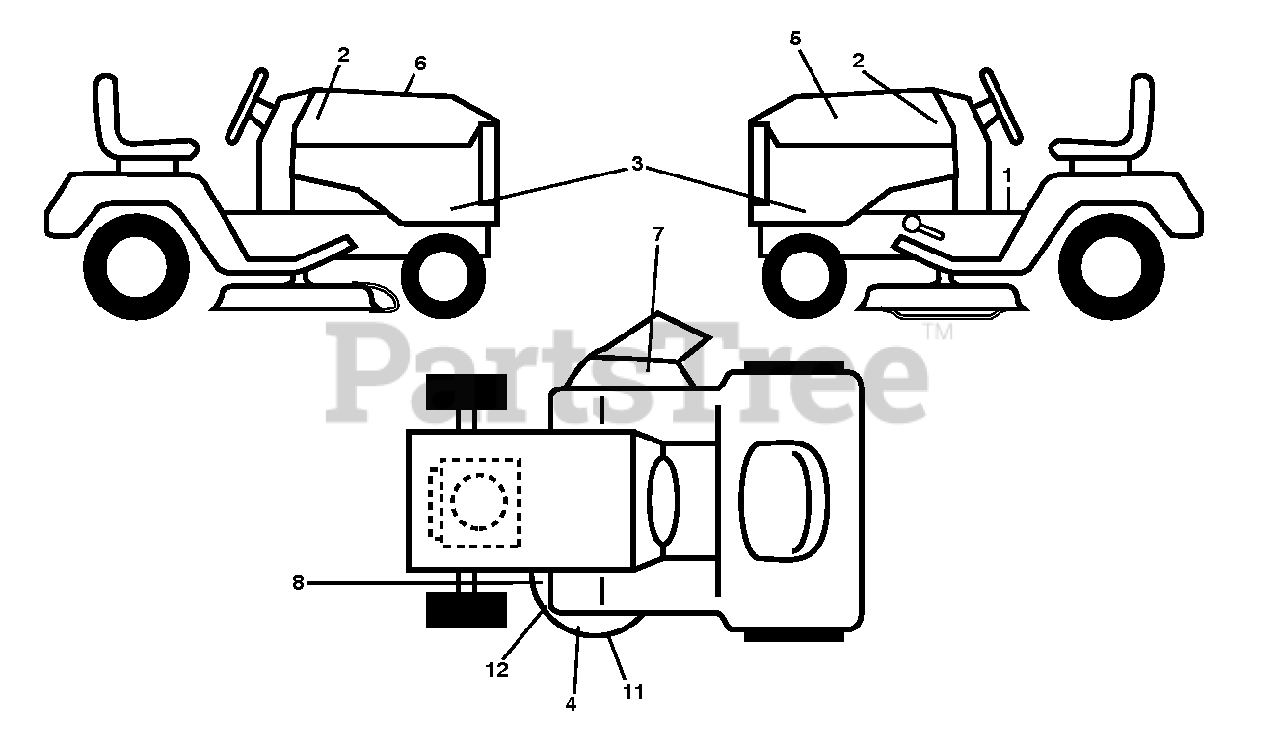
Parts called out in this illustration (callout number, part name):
1	DECAL.WARN.STARTINST.LOWEARIEN
2	DECAL.BADGE.170MM.TEXTLOGO.
3	Decal, Side Panel HUSQGT YT42DXL Set
4	DECAL.DECK.CLEARCUT.NOSTEP
5	DECAL.WARNING.CUST.RESP.E85.
6	DECAL.RPL.KOH.KT7.TLB.42F.K46
7	DECAL.TRACT/ZTR.DECKWARN.HUSQ
8	Deck Decal, WA
11	Deck Decal, 42"
12	DECAL.V-BELT.SCH.42/46"MEC/ELE
